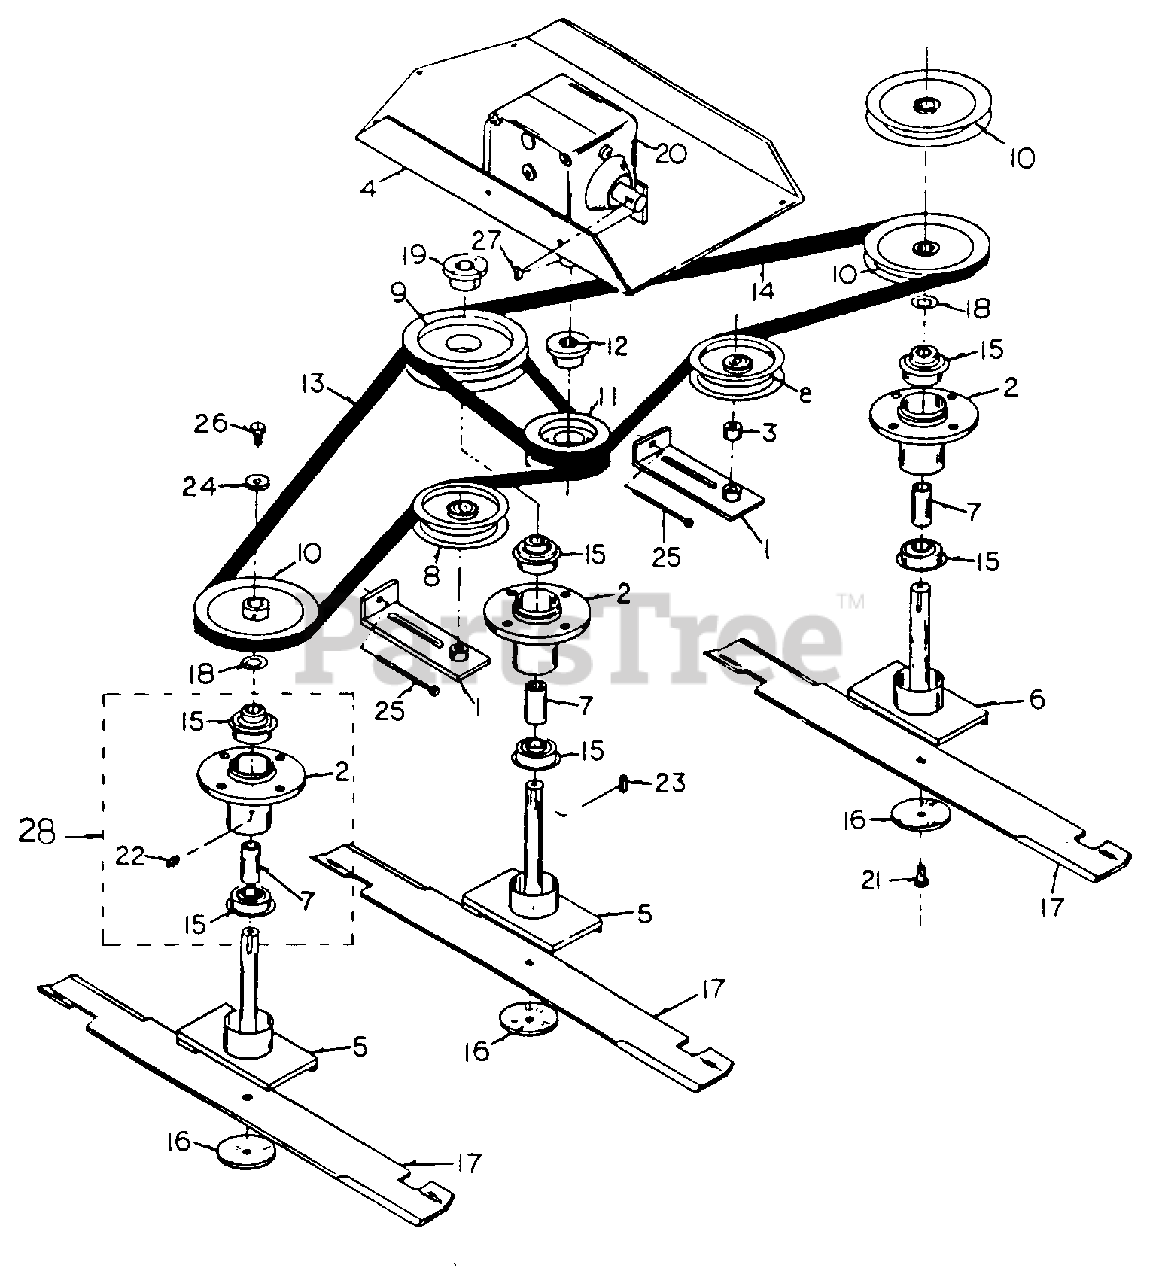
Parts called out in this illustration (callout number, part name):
1	Belt Tightener
2	Houslng Spindle
3	Spacer
4	Gearbox Mount
5	Short Spindle Shaft
6	Long Spindle Shaft
7	Spindle Spacer
9	Double Pulley, 6.2"
10	Single Pulley, 6"
11	Double Pulley, 4.2"
14	Belt, B x 68
15	Spindle Bearlng, 7/8"
18	Mech. Washer, 14GA
19	Taper Hub, 7/8"
21	Hex Bolt, 3/8-24 0 x 1 1/4", GRS
23	Key Stock, 3/16" x 3/16" x 1"
24	Splndle Washer, 5/16", 10 GA 0
25	Hex Tap Bolt, 1/4-20 x 4"
26	Hex Capscrew, 5/16-24 x 3/4"
27	Woodruff Key, 1/4" x 7/8"
28	Spindle Housing Assembly
